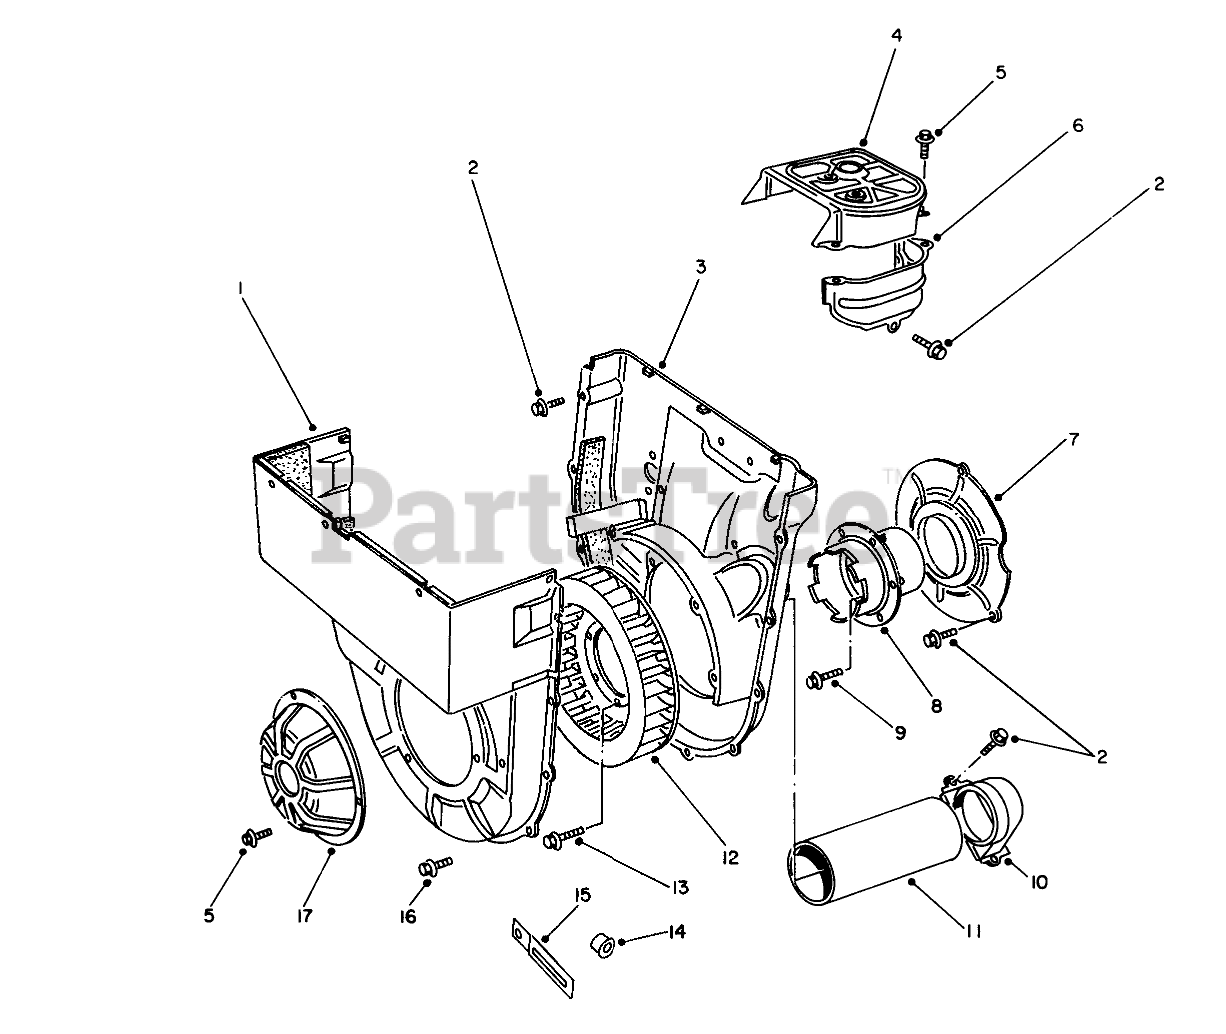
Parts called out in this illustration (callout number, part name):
1	Cover-Cooling Fan Outer
3	Cover-Cooling Fan Inner
4	Cowling-Upper
6	Cowling-Side
7	Cover-Magneto
8	Pulley
10	Guide-Air Duct
11	Tube-Air Duct
15	Clamp-Air Duct
16	SCREW-HHF
17	Cover
